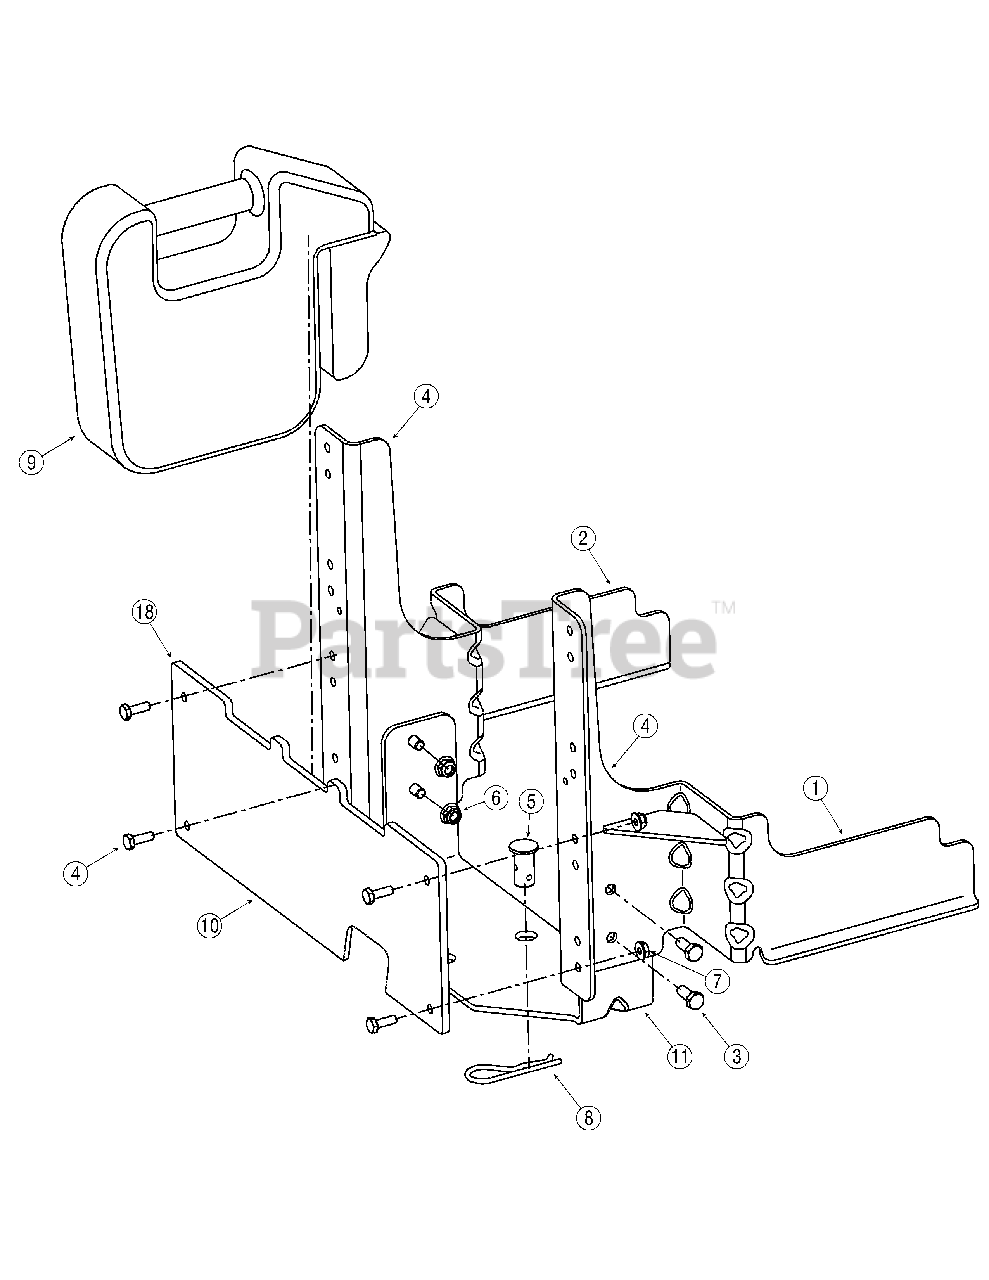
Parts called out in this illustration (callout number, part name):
3	SCREW 5/16-18 x .75 GR5
4	Hex Head Screw, 1/4-20 x .75
5	Clevis Pin, .62 Dia.
6	Flange Lock Nut, 5/16-18
7	Flange Lock Nut, 1/4-20
8	Internal Cotter Pin, .148 x 3.00
9	Suitcase Weight, 45 lbs.
